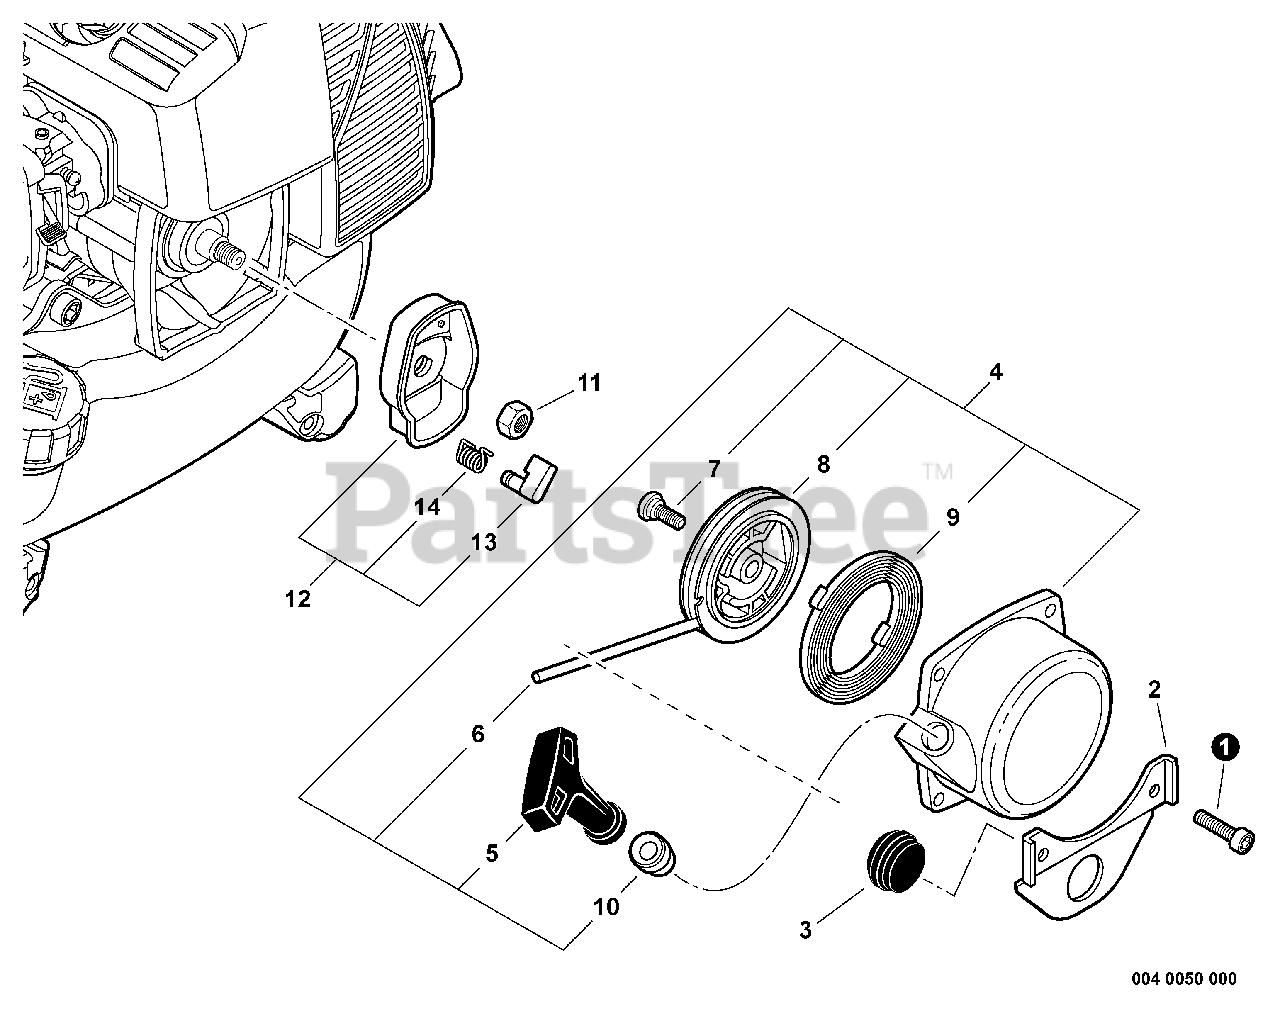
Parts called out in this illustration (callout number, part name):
1	BOLT, TORX 4×16
2	BRACKET, FUEL TANK
3	CUSHION
4	STARTER ASSY, RECOIL
5	GRIP, STARTER
6	ROPE, STARTER 3.0×1000
7	SCREW
8	REEL, ROPE
9	SPRING, RECOIL
10	GUIDE, ROPE
12	PULLEY ASSY, STARTER
13	PAWL, STARTER - BLACK
14	SPRING, RETURN
